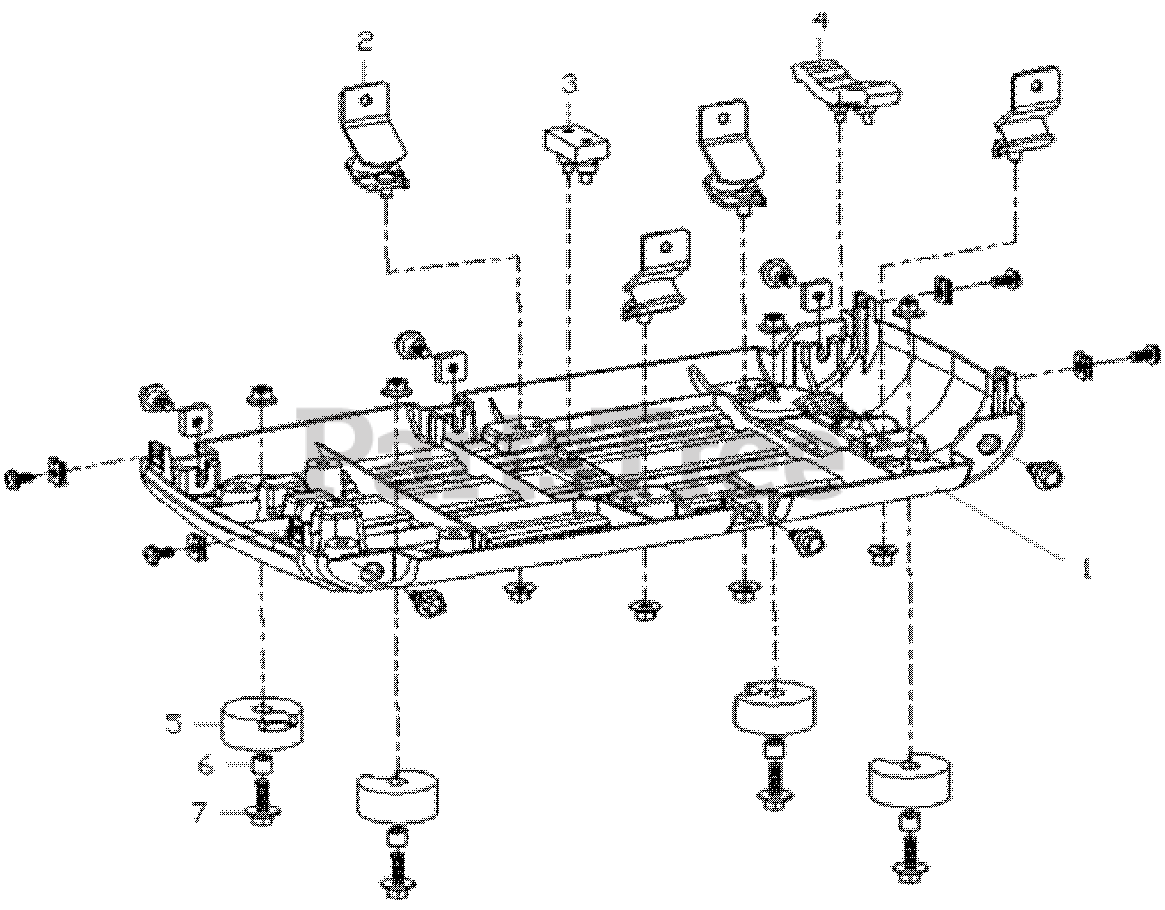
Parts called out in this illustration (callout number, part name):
1	FRAME FLOOR COMBINATION
2	FRAME SHOCK ABSORPTION SEAT
3	BUFFER RUBBER
4	BUFFER RUBBER
5	FRAME SHOCK ABSORPTION SEAT
7	BOLT / GASKET COMBINATION
